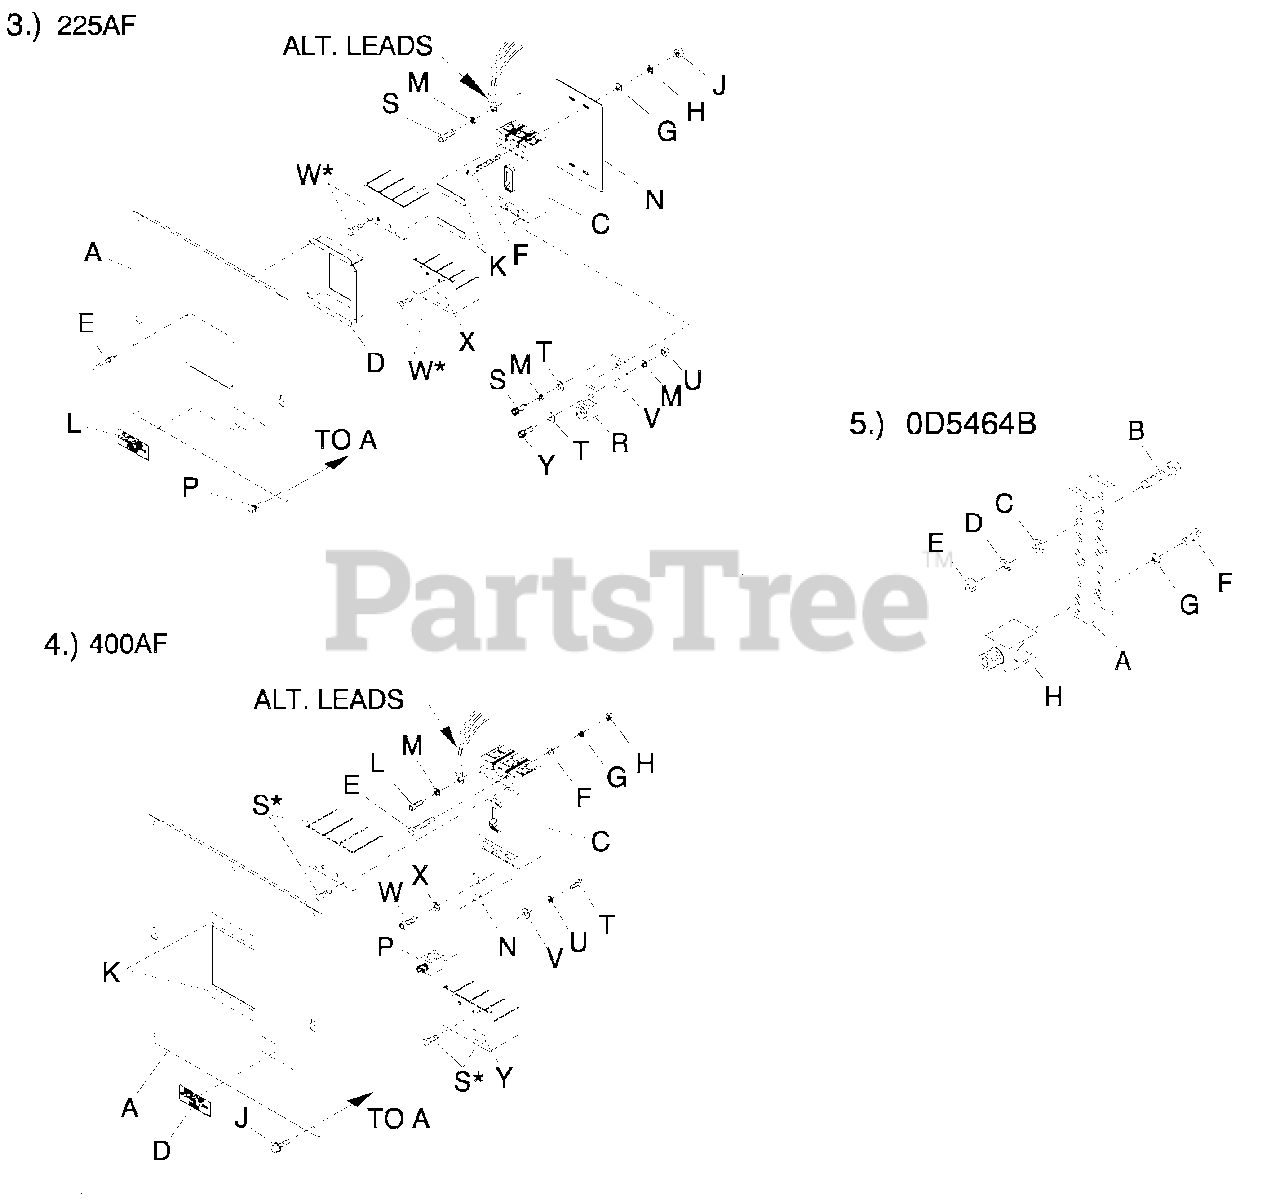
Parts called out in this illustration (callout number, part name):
A	COVER CB C5 225AF
C	CIRCUIT BREAKERS 200A FRAME
D	COVER CB DISH 225AF
E	RIVET POP .125 X .275 SS
F	SCREW RHM #8-32 X 3-1/4
G	WASHER FLAT #8 ZINC
H	WASHER LOCK #8-M4
J	NUT HEX #8-32 STEEL
K	TAPE ELEC 1/2 FOAM
L	DECAL CUSTOMER CONNECT INSIDE
M	WASHER LOCK M8-5/16
N	INSULATOR CB 225AF
P	SCREW THF M6-1 X 16 N WA Z/JS
R	LUG SLDLSS 300 MCM-6 AL/CU
S	SCREW SHC M8-1.25 X 20 G8
T	WASHER FLAT 5/16-M8 ZINC
U	NUT HEX M8-1.25 G8 CLEAR ZINC
V	BUS BAR 200A LUG ADAPTOR
W	TERMINAL COVER CB
X	DECAL TERMINAL SHOCK HZD BI
Y	SCREW SHC M8-1.25 X 25 G12.9
A	COVER CB C5 400AF
C	CIRCUIT BREAKERS 400A FRAME
D	DECAL CUSTOMER CONNECT INSIDE
E	SCREW RHM 10-32 X 4
F	WASHER FLAT #10 ZINC
G	WASHER LOCK #10
H	NUT HEX #10-32 STEEL
J	SCREW THF M6-1 X 16 N WA Z/JS
L	SCREW SHC M10-1.5 X 25 G12.9
M	WASHER LOCK M10
N	BUS BAR CB ADAPTER 225-400 A
P	LUG SLDLSS 600/250-1/0 X 1/4-28
R	WASHER FLAT 3/8-M10 ZINC
S	TERM COVER CB
T	SCREW HHC 1/4-28 X 1/2 G5
U	WASHER LOCK M6-1/4
V	WASHER FLAT 1/4-M6 ZINC
Y	DECAL TERMINAL SHOCK HZD BI
A	COVER CB C5 800AF
C	CIRCUIT BREAKERS 800A FRAME
D	INSULATOR CB 800AF
E	SCREW RHM 1/4-20 X 3-1/2
F	WASHER FLAT 1/4-M6 ZINC
G	WASHER LOCK M6-1/4
H	NUT HEX 1/4-20 STEEL
J	SCREW THF M6-1X16 N WA Z/JS
L	SCREW SHC M10-1.50 X 40 G12.9
M	WASHER FLAT 3/8-M10 ZINC
N	WASHER LOCK 3/8
P	NUT HEX M10-1.5 G8 YEL CHR
R	LUG SLDLSS 3/0-400X3 MCM AL/CU
S	SCREW SHC M6-1.0 X 50 G8.8
T	DECAL CUSTOMER CONNECT INSIDE
U	TERM COVER VITZROTECH 400AF CB
V	DECAL TERMINAL SHOCK HZD BI
W	WASHER LOCK M6-1/4
A	BUS BAR NEUTRAL BLOCK 390
B	SCREW HHC M8-1.25 X 45 G8.8 FT
C	WASHER FLAT 5/16-M8 ZINC
D	WASHER LOCK M8-5/16
E	NUT HEX M8-1.25 G8 YEL CHR
F	SCREW HHC 1/4-28 X 3/4 G5
H	LUG SLDLSS 600/250-1/0X1/4-28
